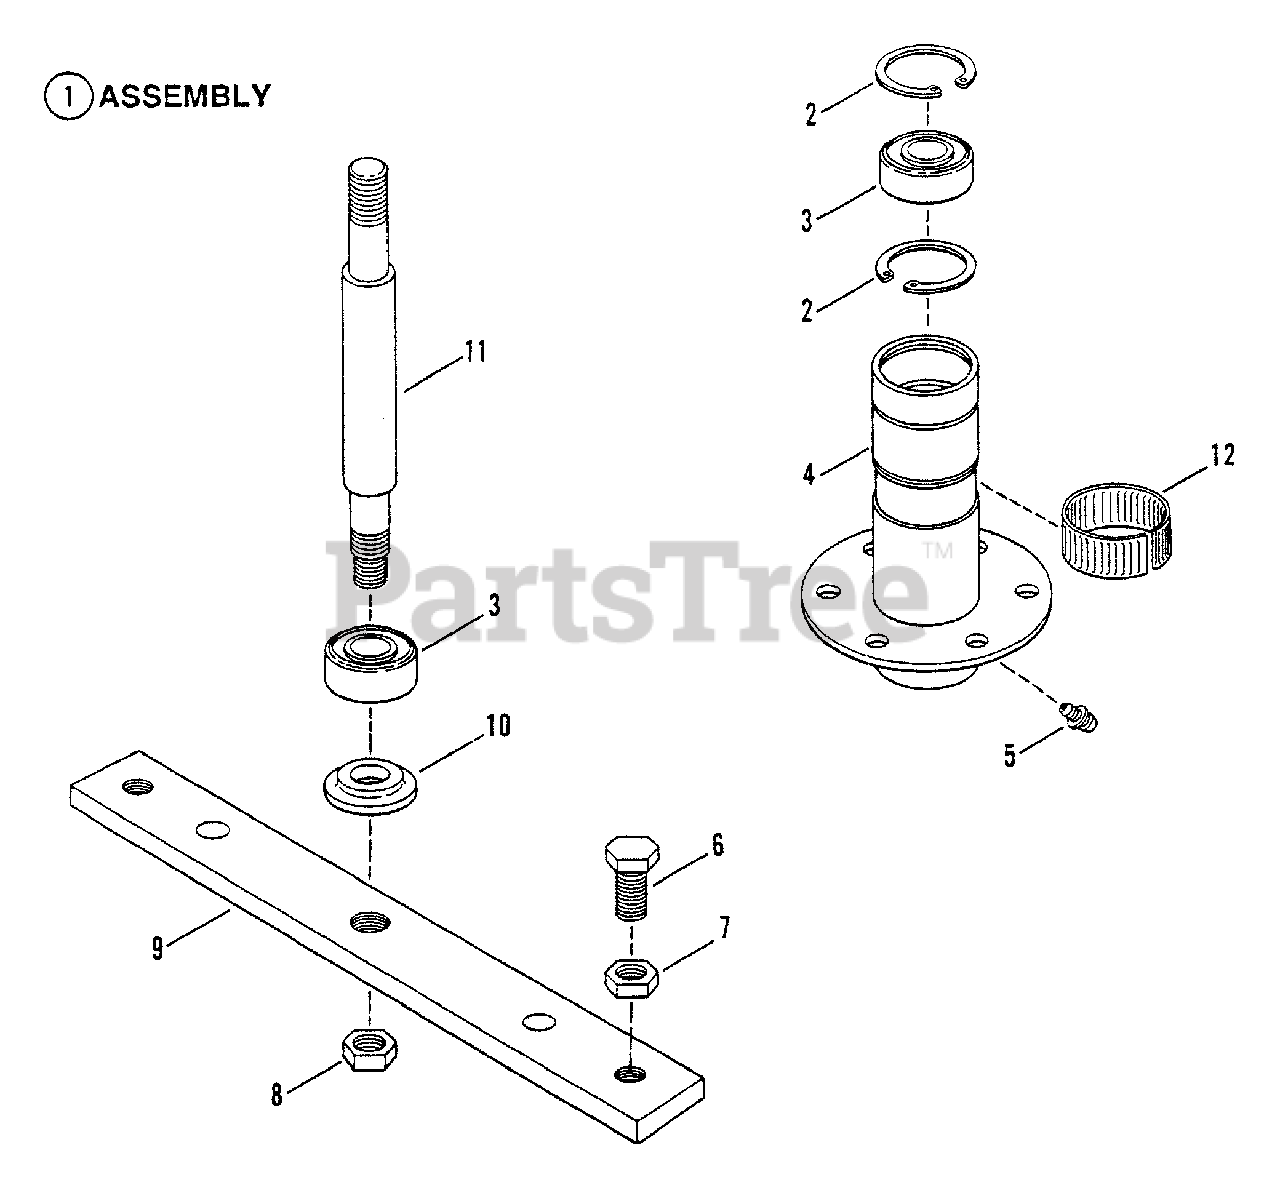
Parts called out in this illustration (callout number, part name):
1	ASSEMBLY, Spindle Housing, 33" Cutting Deck
2	RING, Retaining
3	BEARING, Spindle
4	HOUSING, Spindle
5	FITTING, Lube (Press fit for .187 hole-no ball)
6	SCREW, 1/2-20 x 1" Hex Head Cap, (Gr. 5)
7	NUT, 1/2-20 Hex Jam
8	NUT, 5/8-18 Hex Lock
9	HOLDER, Blade
10	WASHER, Spindle
11	SPINDLE 7.54"
12	RING, Tolerance
